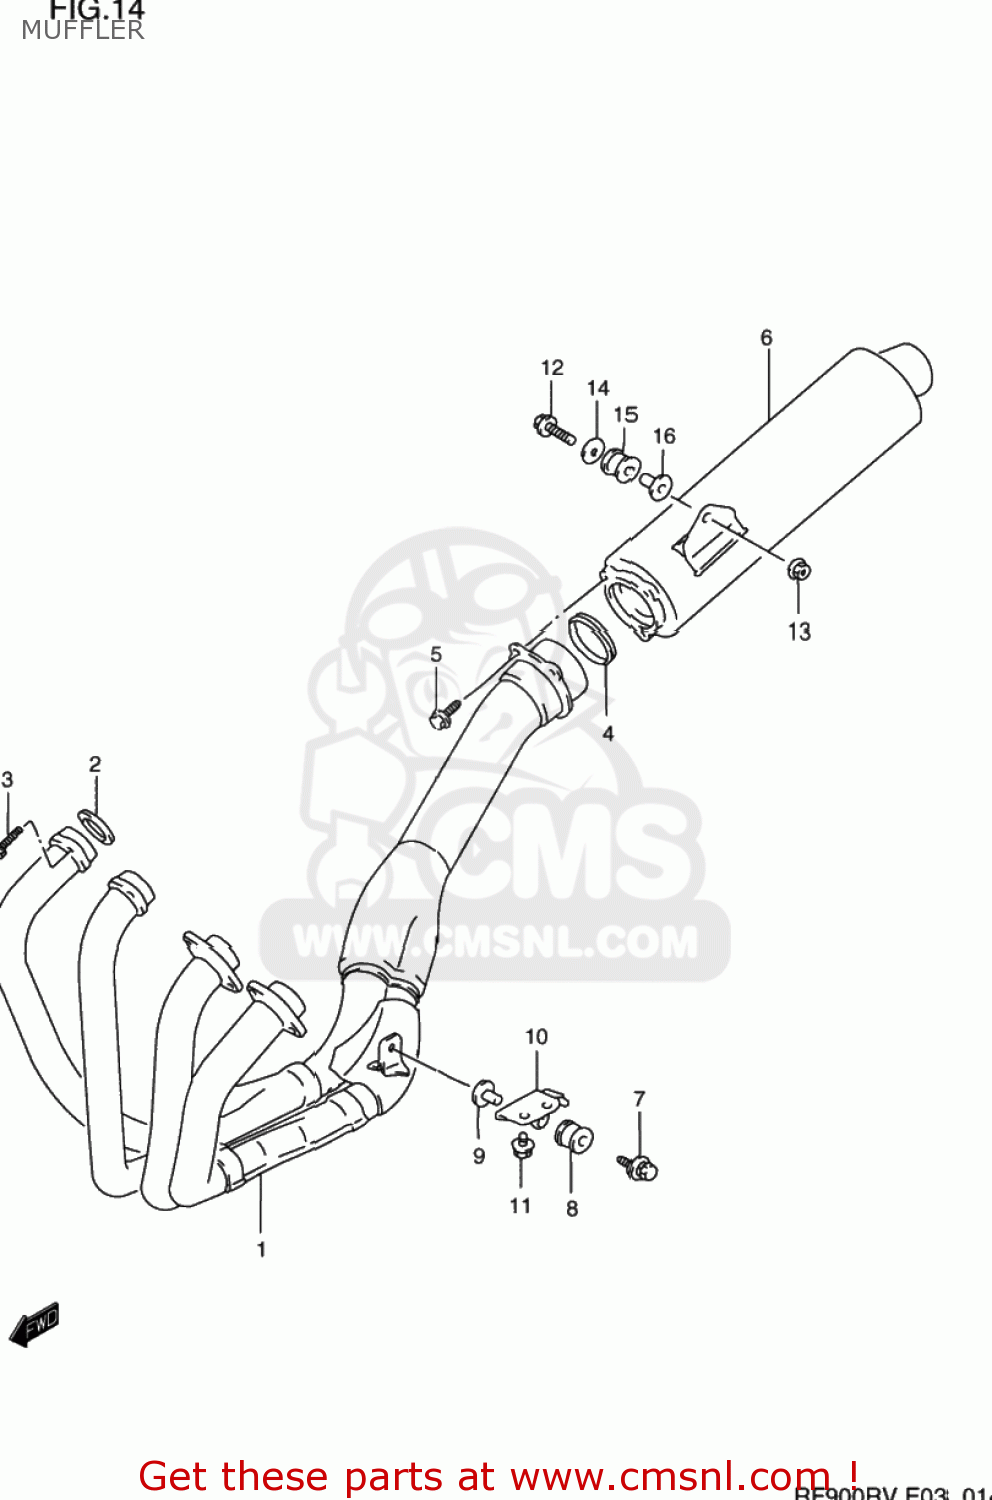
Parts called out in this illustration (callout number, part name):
1	PIPE,EXHAUST
2	GASKET,EXHAUST PIPE
3	BOLT
4	GASKET,MUFFLER JOINT
5	BOLT(8X20)
6	BODY,MUFFLER
7	BOLT 8X45
8	CUSHION
9	SPACER(8.6X12X24.2)
10	BRACKET,MUFFLER SUPPORT FR
11	BOLT
12	BOLT
13	NUT
14	WASHER (8.1X33X1.6)
15	CUSHION
16	SPACER(8.6X12X27.1)
